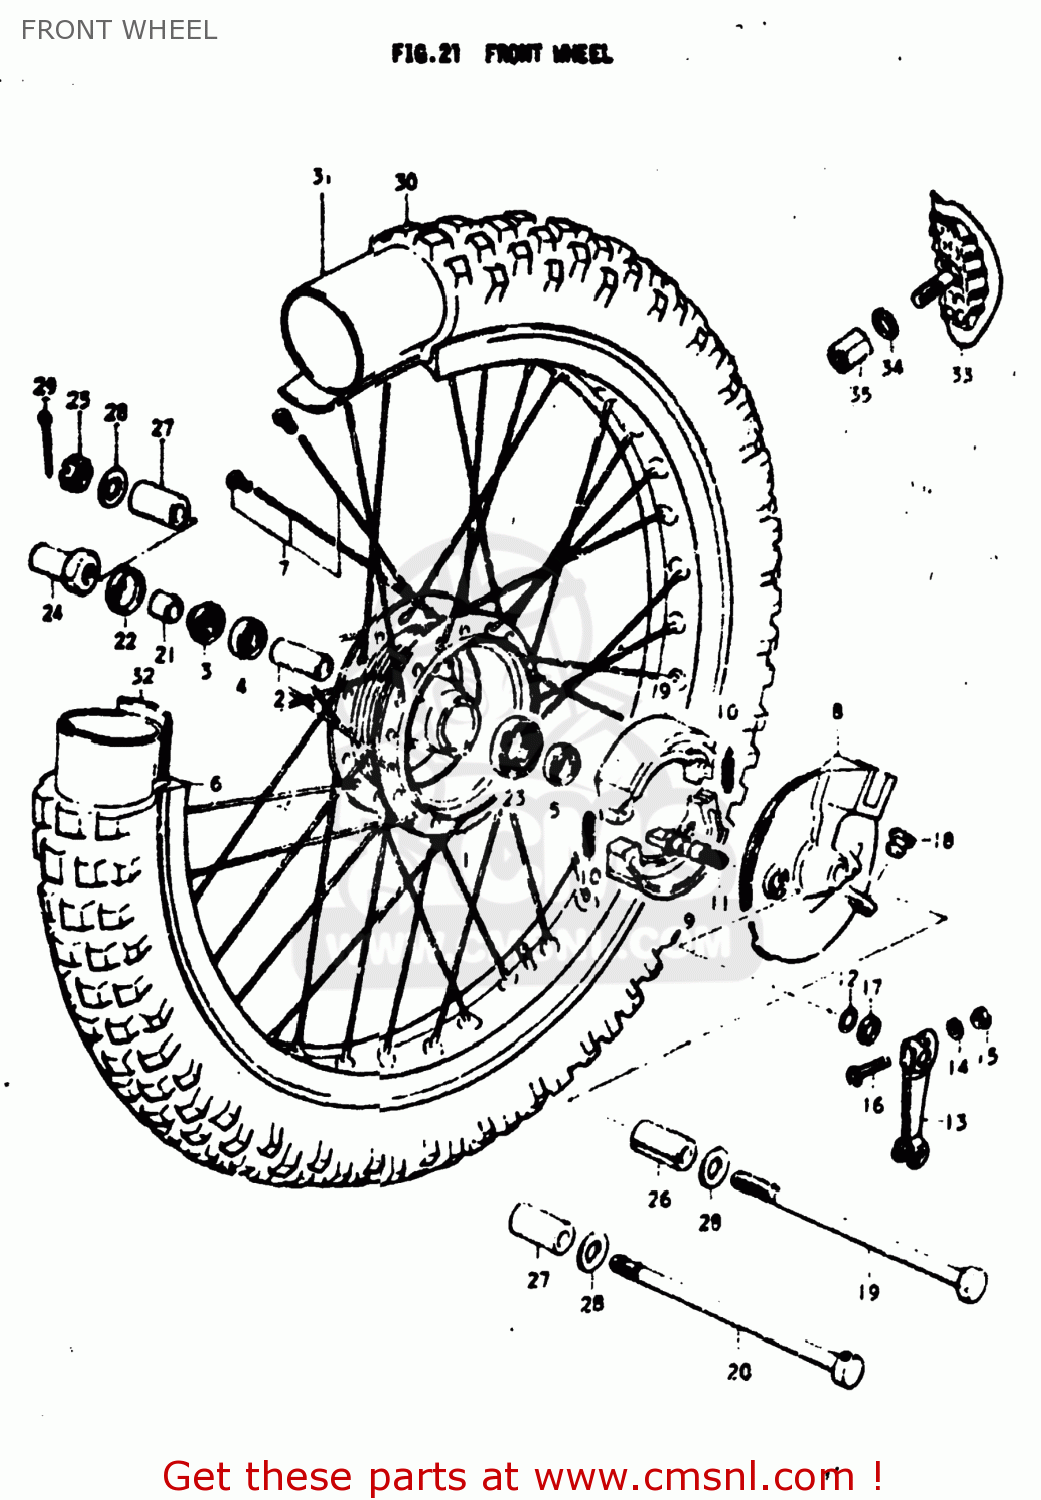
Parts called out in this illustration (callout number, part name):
0	HUB,FRONT
1	HUB,FRONT
2	SPACER (12.6X19X52)
3	OIL SEAL
4	BEARING
5	BEARING, LH
6	RIM,FRONT WHEEL
7	SPOKE SET,FRONT
8	PANEL,FRONT HUB
9	SHOE,BRAKE
10	SPRING(L:34)
11	CAM,FR BRAKE
12	O RING(D:2.5,ID:11.4)
13	LEVER,FR BRAKE CAM
14	WASHER
15	NUT
16	BOLT
17	WASHER(12.5X20X1)
18	CAP(OD:17)
19	AXLE,FRONT
20	AXLE,FRONT
21	SPACER
22	DUST SEAL,FRONT HUB DRUM
23	OIL SEAL (43X58X7)
25	NUT, REAR AXLE
26	SPACER,FRONT AXLE,LEFT
27	SPACER
28	WASHER
29	COTTER PIN
30	TIRE,FRONT
31	TUBE
32	PROTECTOR,WHEEL,INNER
33	STOPPER,BEAD
34	WASHER
35	NUT
